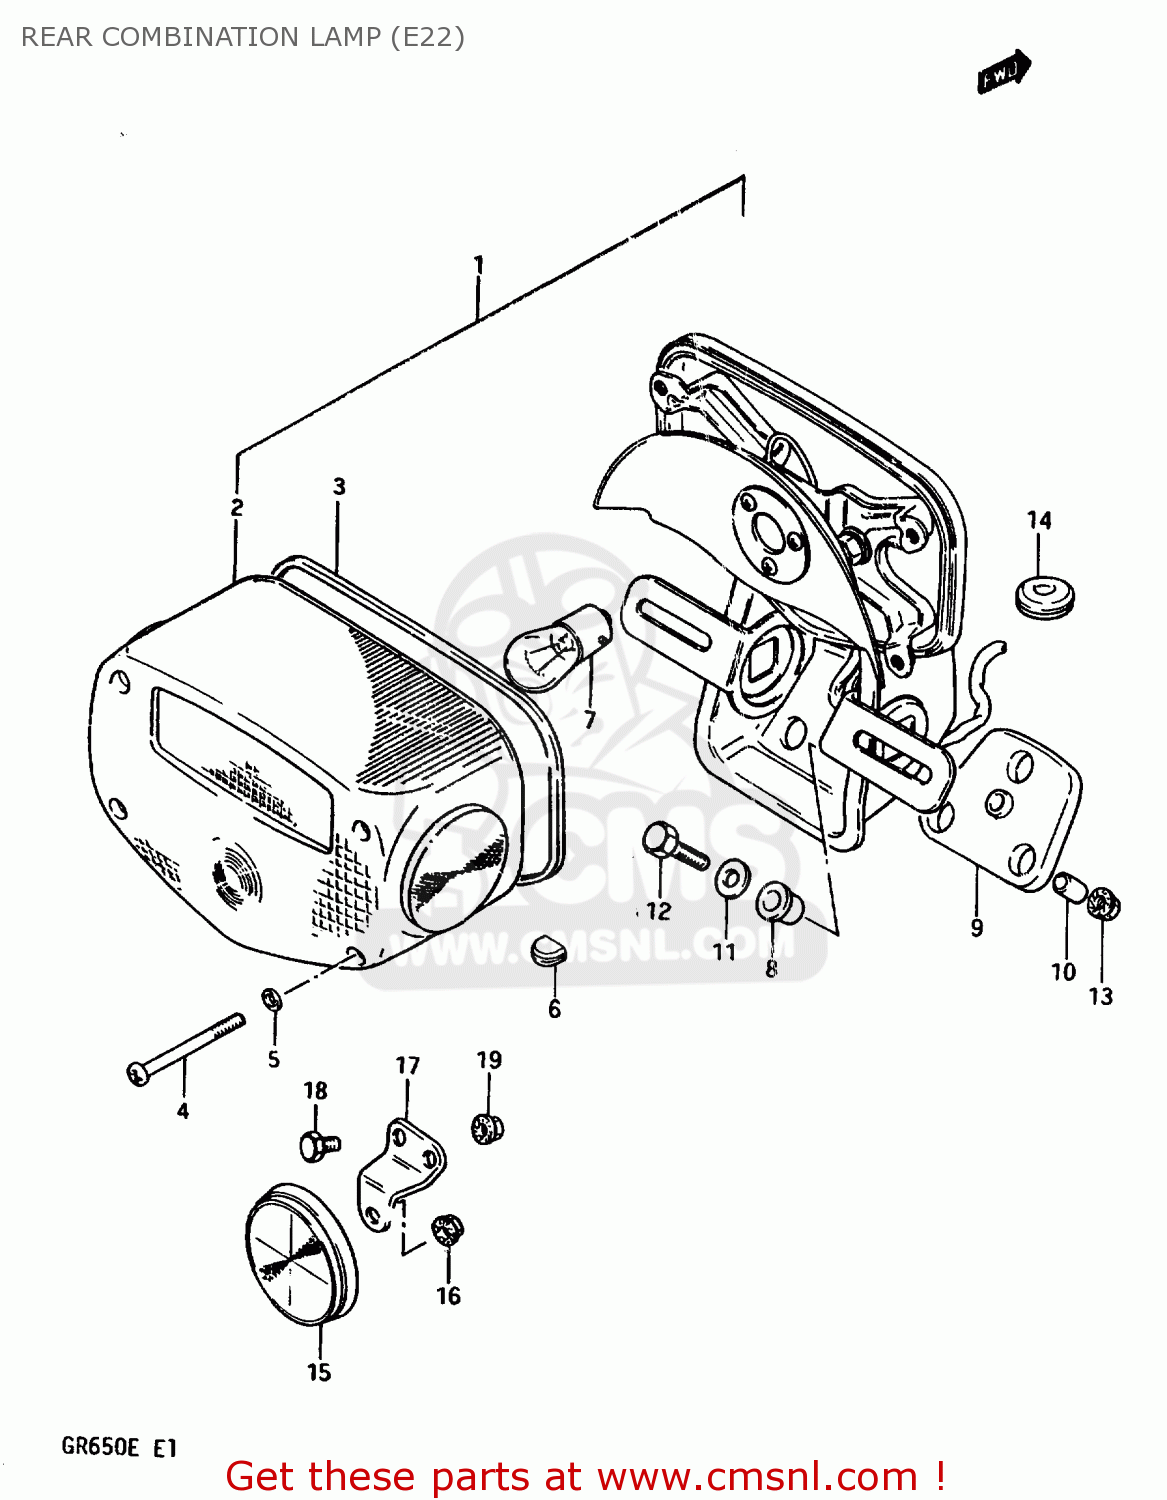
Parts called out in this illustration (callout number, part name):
1	LAMP ASSY, REAR COMBINATION
2	LENS,RR COMBIN
3	GASKET (NAS)
4	SCREW (4X55)
5	GASKET (NAS)
6	GROMMET
7	BULB(12V21/5W)
8	CUSHION
9	CUSHION
10	SPACER
11	WASHER (6.5X20X1.2)
12	BOLT
13	NUT 6MM
14	GROMMET
15	REFLEX REFLECTOR,RR
16	NUT 5MM
17	BRACKET, REAR RR.
18	BOLT 5X10
19	NUT 5MM
